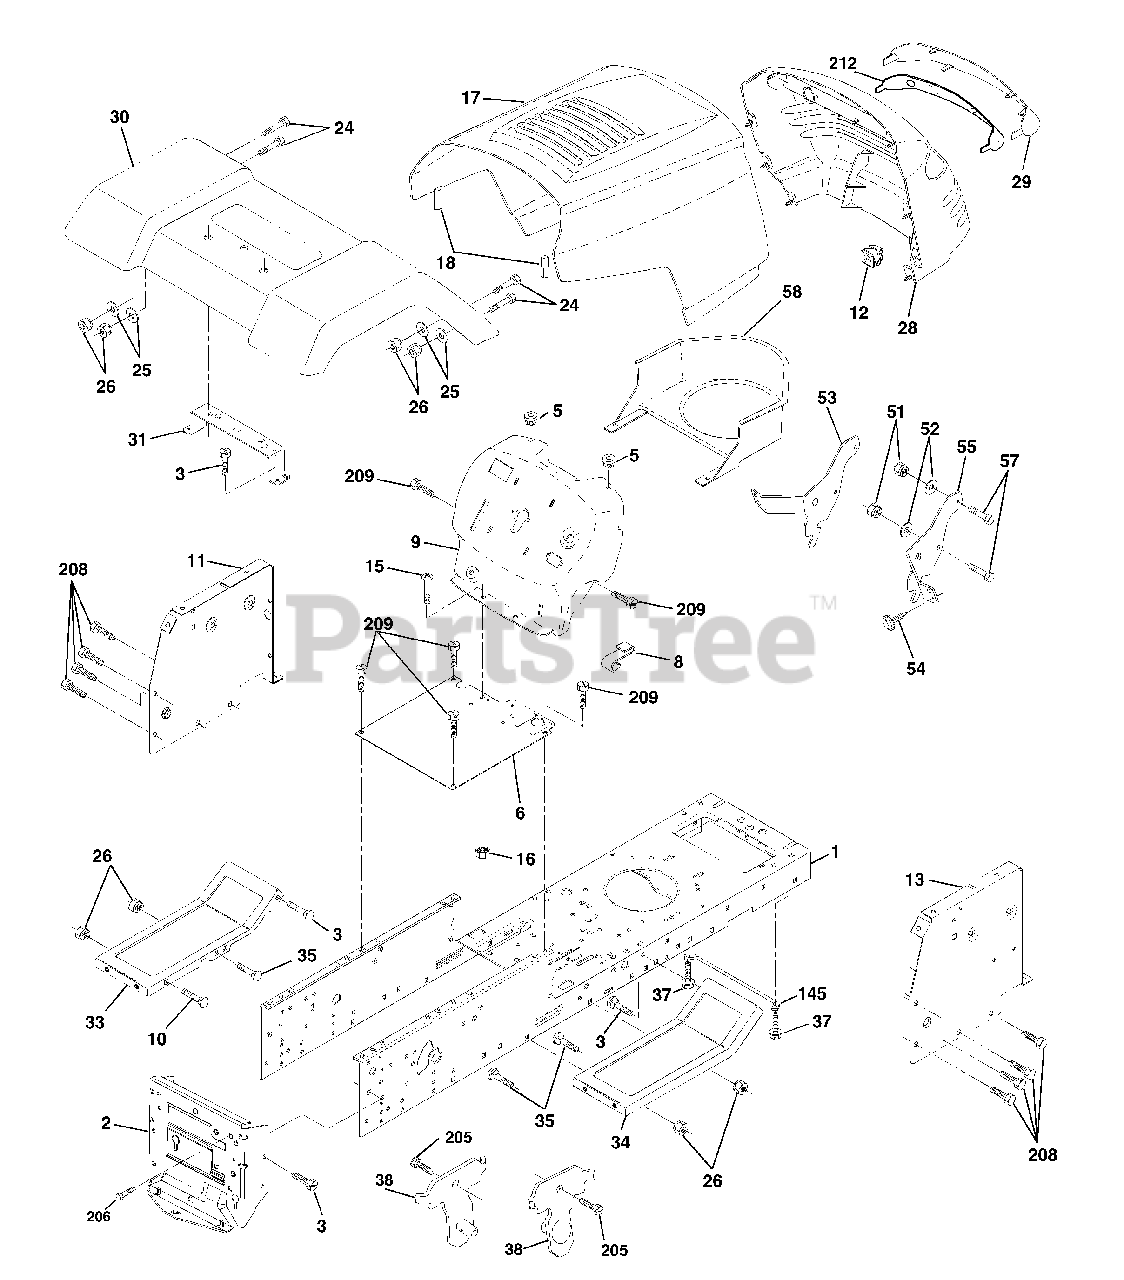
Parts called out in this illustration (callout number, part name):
1	Chassis
2	Drawbar, Stretch
3	Screw 3/8-16 x 3/4
5	Bumper,Hood/Dash
6	Saddle Silkscreen Flt Sdl
8	Clip Retainer Slide-On
9	Dash
10	Bolt, Carriage 3/8-16 x 1
11	Panel Dash LH
12	Clip Tinnerman Grille P.L
13	Panel Slkscr Dash RH
15	Screw Mach TRHD 5/16-18uncx3/4
16	Nut Keps 5/16-18 Unc
17	Hood
18	Bumper Hood
24	Bolt Fin Hex 3/8-16unc X 1 Gr. 5
25	Washer 13/32 X 13/16 X 12 Ga
26	Nut Lock Hex w/Ins 3/8-16 Unc
28	Grille P.L Ms 428
29	Lens Grille Private Label
30	Fender
31	Bracket Fender Repl 109873x
33	Footrest Pnt LH Perf
34	Footrest Pnt RH Perf
35	Bolt Rdhd Sht Sqnk 3/8-16 X3/4
37	Screw Thdrol 5/16-18 x 1/2 TYT
38	Bracket Asm. Pivot Mower Rear
51	Nut Lock W/Insert 1/4-20unc
52	Washer 9/32 x 7/8x16 Ga.
53	Bracket Grille Lh
54	Screw Hex 8-18 x 7/8
55	Bracket Grille Rh
57	Bolt Fin Hex 1/4-20 unc x .75
58	Duct Air Engine PL/LT
145	Rod Pivot Chassis/Hood
205	Screw Thdrol 3/8-16 x 1/2
206	Bolt Shoulder 5/16-18
208	Screw Thdrol 3/8-16 x 1/2
209	Screw Hex Wsh Thdrol 3/8-16
212	Insert Lens Reflect
